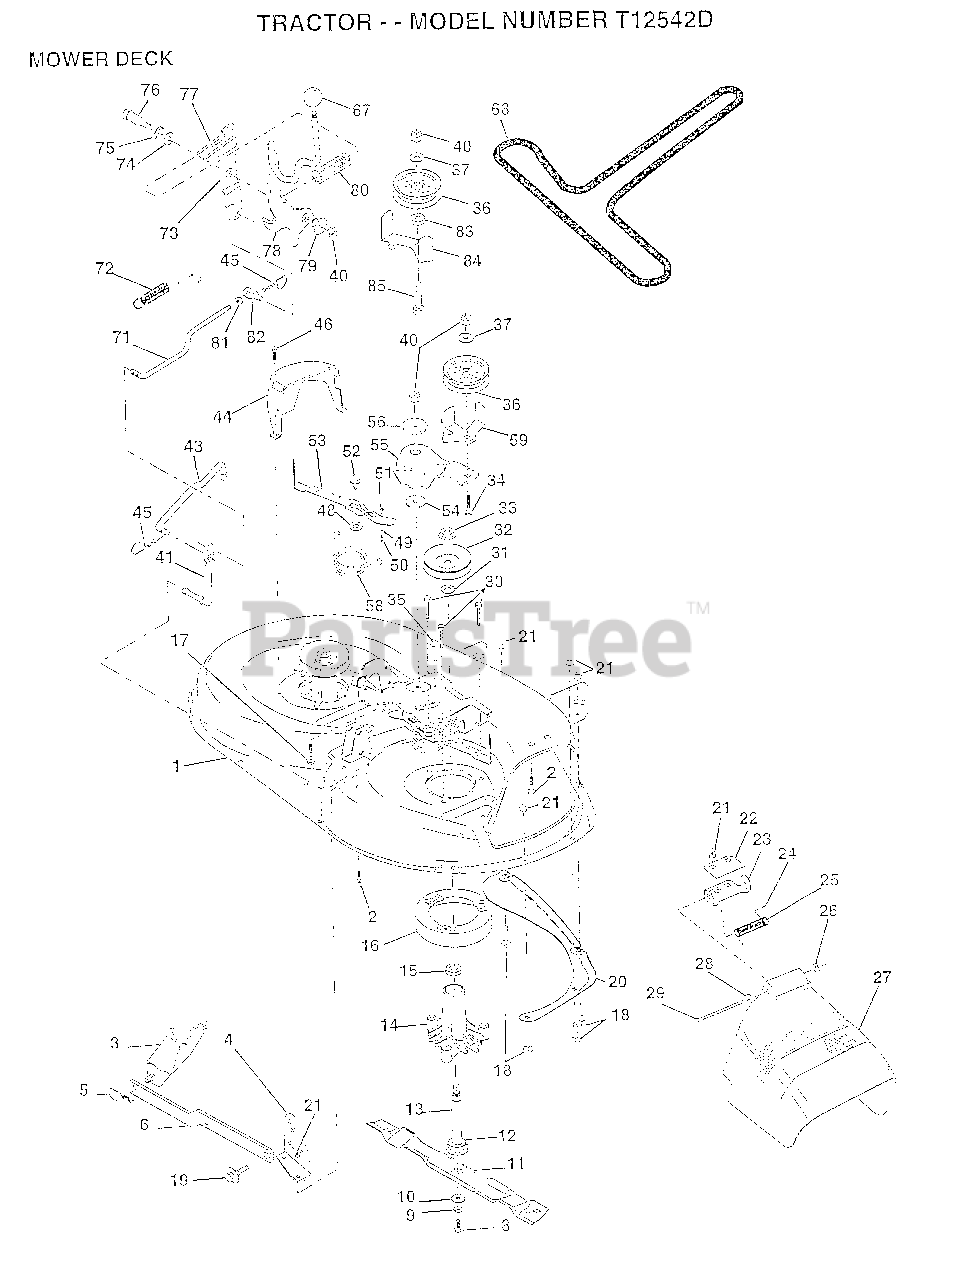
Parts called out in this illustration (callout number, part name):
1	DECK.WELD.42.
2	BOLT
3	BRKT ASM SWAY BAR
4	BRKT DECK SW BAR
8	BLADE BOLT
10	WASHER.HARD.BLADE
11	"BLADE.42"" HIPERF"
12	BEARING.BALL
14	HSG ASM MANDREL
15	BEARING
16	STRIPPER RND MWR
17	BOLT RDHD 3/8-16
18	BOLT
19	BOLT SHD 5/16-18
22	STIFFENER BRKT
23	DEFLECTOR BRKT
25	SPRING TORSION
27	DEFLECTOR.SHIELD
28	WASHER
29	HINGE ROD
31	WASHER
32	PULLEY.MANDREL.42
34	BOLT
35	XMAS TREE FASTNER
36	FLAT IDLER PULLEY
37	WASHER
41	PIVOT ROD
43	ROD CLUTCH W/NIBS
44	GUARD MAND LH BLK
46	SCREW.1/4-20X5/8
48	HARD SMALL WASHER
50	SHOULDER BOLT
51	LOCKNUT
52	BOLT.SHLD.5/16-18
53	BRAKE PAD ARM ASM
54	HARDENED WASHER
56	SPACER RETAINER
58	SPRING TORSN BRAK
59	GUARD IDLER TUV
67	CONTROL KNOB LT
68	BELT.V.T-PATH
71	ROD CLUTCH 38/42
72	RETURN SPRING
74	WASHER
75	RING
76	SHOULDER BOLT
77	SPRING KEEPER
78	LEVER ASM CLT PRM
79	BUSHING
81	NUT
82	TRUNION ADJ
83	WASHER
85	BOLT RDHD 3/8-16
